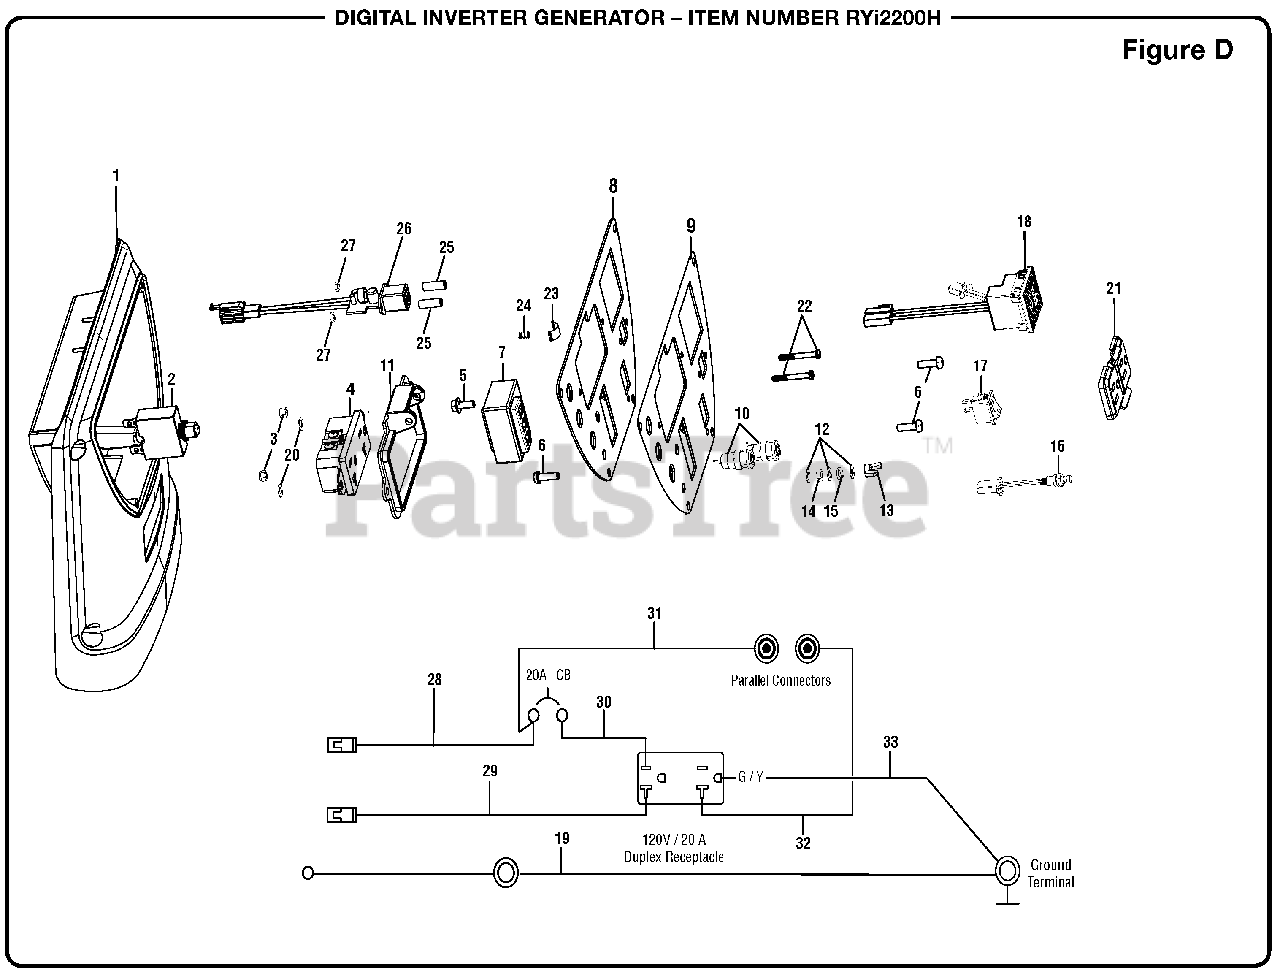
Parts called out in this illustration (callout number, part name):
1	Front Cover w/Labels & Foam
2	Circuit Breaker (20A)
3	Hex Nut (M4)
4	120 Volt Duplex Receptacle (20 Amp)
5	Screw (M5 x 12 mm, Flange Hd)
6	Bolt (M5 x 16 mm, Pan Hd)
7	Ignition Module
8	Control Panel
9	Front Panel Label
10	Connector (Black)
11	Receptacle Cover (Back)
12	Flat Washer (OD10 x ID53 x 05t)
13	Wing Nut (M5)
14	Hex Nut (M5)
15	Lock Washer (OD9 x ID5 x 13t)
16	Reset Button
17	Auto Idle Switch
18	12V DC Receptacle
19	Wire Lead (14AWG-220 mm, Yellow-Green)
20	Flat Washer (OD10 x 42 x 1t)
21	Receptacle Cover (Front)
22	Screw (M3 x 25 mm, Phillips Pan Hd )
25	Spacer (172 mm)
26	Circuit Board (USB PORT CHARGER)
28	Wire Lead (14 AWG-220 mm)
29	Wire Lead (14 AWG-220 mm w/Dj441-4B)
30	Wire Lead (14 AWG-110 mm w/Dj441-4B)
31	Wire Lead (14AWG-80 mm)
32	Wire Lead (14AWG-110 mm W/Dj622-D6-3B)
33	Wire Lead (14AWG-120 mm)
